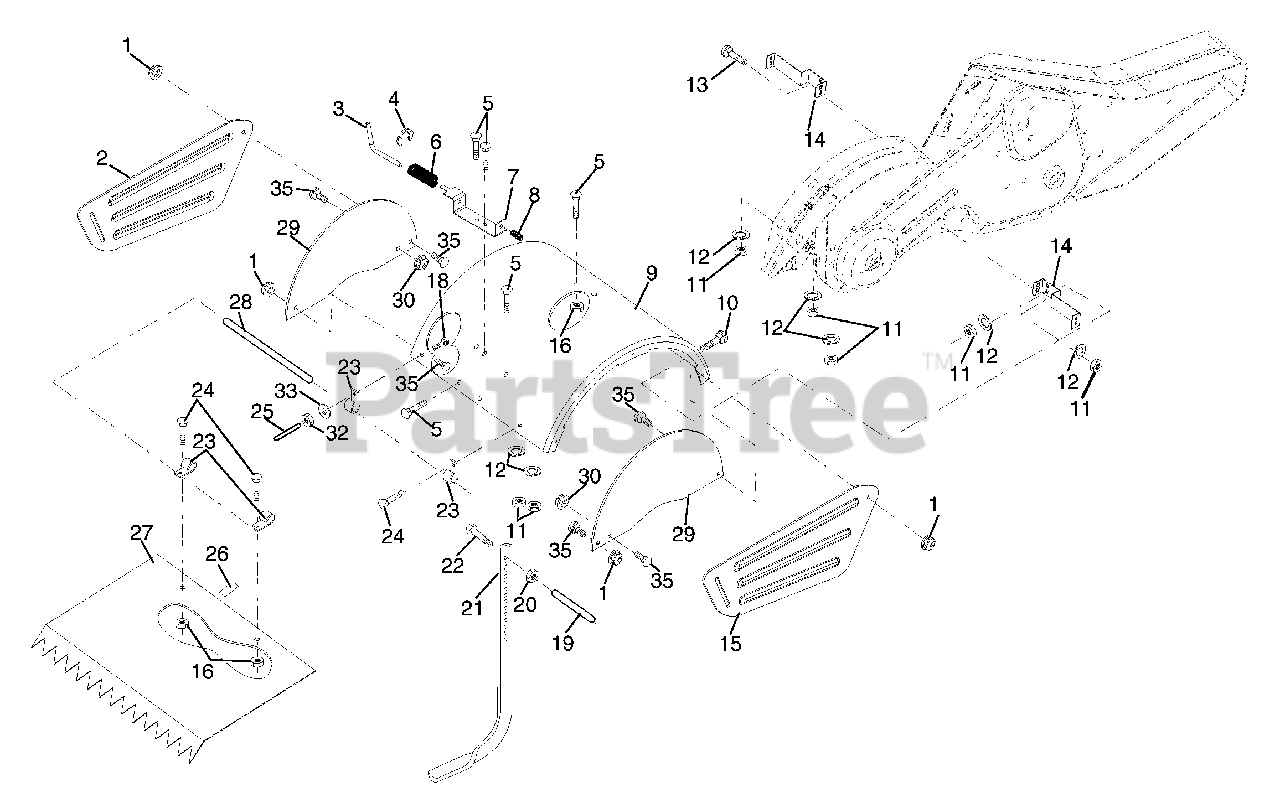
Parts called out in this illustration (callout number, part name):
1	Nut, Lock Hex Flange 5/16-18
2	Shield, Side, Outer L. H.
3	Pin, Stake, Depth
4	Ring, Klip
5	Bolt 5/16-18 unc x 1
6	Spring
7	Bracket, Latch
8	Spring, Depth Stake
9	Shield, Tine
10	Bolt 5/16-18 x 3/4 ZNC
11	Nut, Hex 5/16-18
12	Washer, Lock 5/16
13	Bolt, Carriage 5/16-18 x 1-1/4
14	Bracket, Shield Tine
15	Shield, Side, Outer R.H.
16	Nut, Hex Flange 1/4-20 unc
18	Bolt, Carriage 1/4-20 x 1-1/4 Gr. 5
19	Grip
20	Nut, Hex 3/8-16
21	Stake, Depth
22	Bolt, Hex 3/8-16 x 2
23	Hinge
24	Bolt, Carriage 1/4-20 x 1/2 Gr. 5
25	Cap, Vinyl
26	Pad, Idler
27	Shield, Leveling
28	Pin, Hinge
29	Shield, Side
30	Locknut, Flange 5/16-18
32	Nut Fin Hex 1/4-20 unc
33	Washer Lock Hvy Helical 1/4
35	Bolt Carr. 5/16-18 x 5/8
